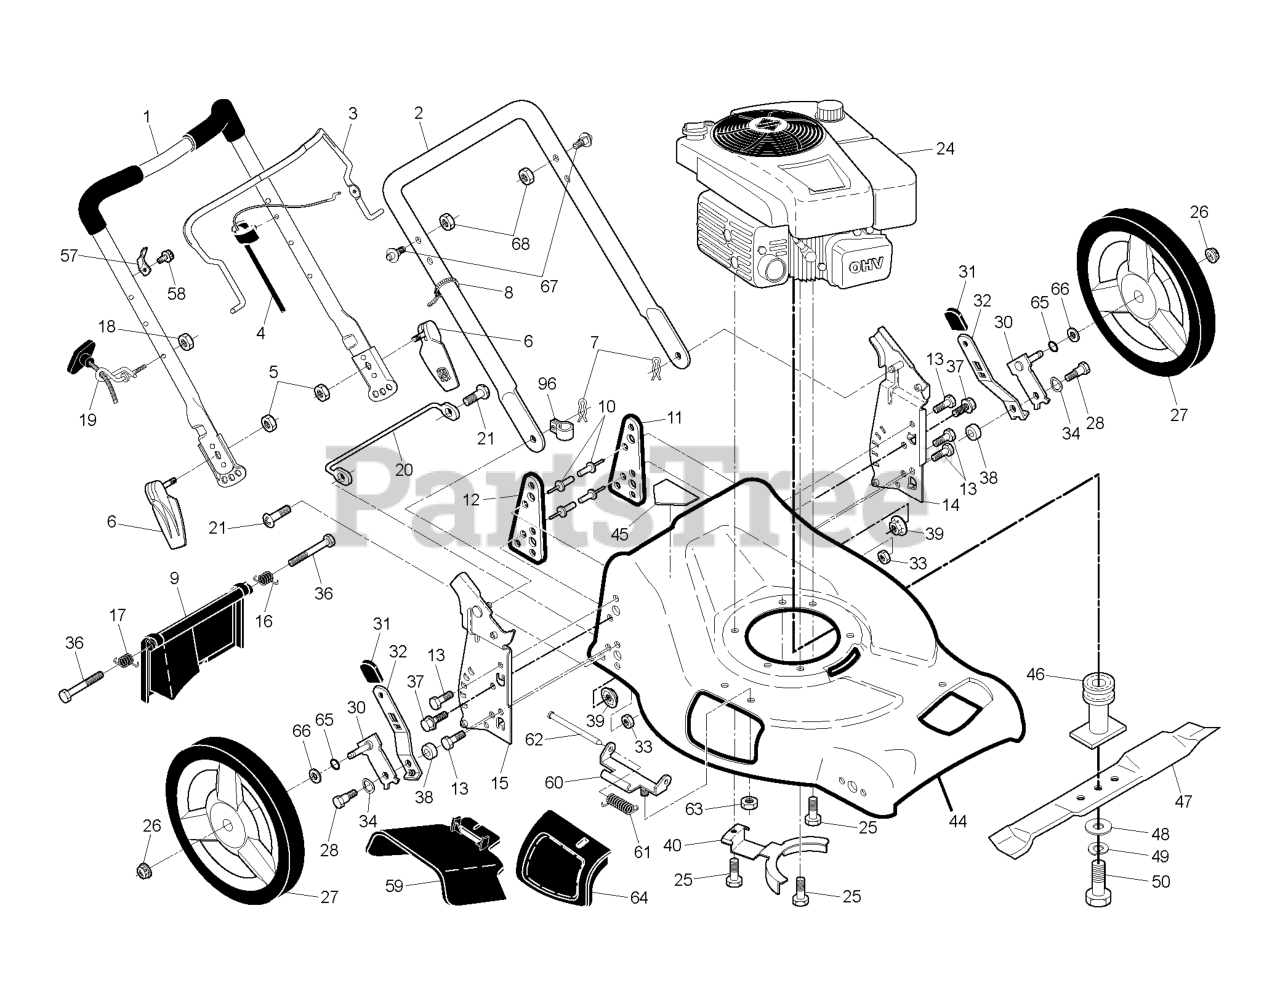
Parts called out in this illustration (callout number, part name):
1	HANDLE.ASM.UP.W/ADJ.BKT.21FGD
2	HANDLE.ASM.LOWER.21.NB.GREY
3	BAIL.CONTROL.MZR.BS.ORANGE
4	CABLE.ASM.ZONE.CONTROL
5	NUT.HEX.FLANGE.1/4
6	HANDLE KNOB ASM,QUICK REL BLK
7	HAIRPIN COTTER
8	TIE GUIDE
9	REAR DOOR ASSEMBLY
10	RIVET BLIND
11	SUPPORT BRACKET LH
12	BRACKET.SUPRT.RH.21.FWGD
13	SCREW 14-20 X 5/8
14	BRACKET.ASM.HDL.LT.21FGD.HW.OR
15	BRACKET.ASM.HDL.RT.21FGD.HW.N
16	SPRING.REAR.DOOR.EZ.21.LT
17	SPRING.REAR.DOOR.EZ.21.RT
18	NUT
19	RB GUIDE.ROPE.STD.BLK.ZIN WSL
21	SCREW
25	BOLT 3/8-16X1-1/8
26	NUT.HEX.FLANGE.3/8-16.LOCKNUT
27	WHEEL ASSY
28	SHOULDER BOLT 5/16-18
30	ARM.ASM.AXLE.REAR.5/9.POS.BZP
31	SELECTOR KNOB
32	SELECTOR SPRING
33	NUT.71038.31-18.HEX.NYLOCK
34	WASHER.CURVED.CYLINDRICAL
37	BOLT.FIN.HEX.5/16-18X3/4
38	SPACER.HEIGHT.ADJUSTER
39	NUT.FLANGE.5/16
40	BRACKET.KEEPER.BELT
44	KIT.HSG.21.FGD.MC.ORG.CE SYM
45	DECAL.INTERNATIONL.CUTFINGER
46	RB ADAPTER.BLADE.25MM.VS.LOW
47	BLADE.21.PUSH
48	WASHER,HARDEN
49	LOCKWASHER
50	SCREW, HEX HD 3/8-24 X 1-3/8
57	BRACKET.UPSTOP.RT
59	DEFLECTOR.CLIPPIN.21.FGD
60	BRACKET.ASM.HINGE.21.FWGD.
61	SPRING.TORSION
62	ROD.HINGE.21
63	LOCKNUT.NYLOC.1/4-20
64	DOOR.MULCH.21.REAR.FWGD
65	O-RING..070X.487.NEOPRENE
66	WASHER.FLAT.1/2
67	STUD.QUICK.ADJUST
68	NUT.LOCK.5/16-18
96	CLIP.CABLE.BLK
